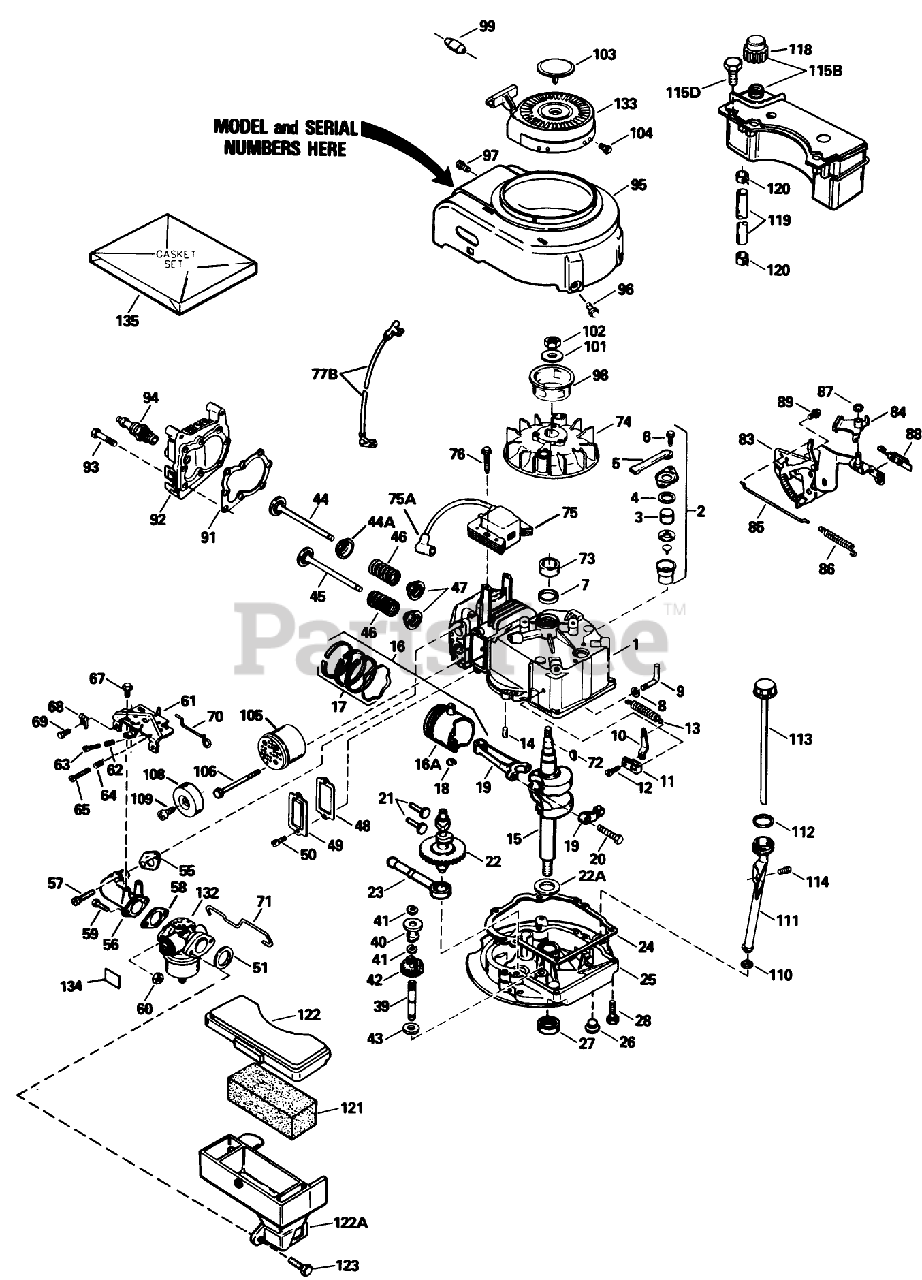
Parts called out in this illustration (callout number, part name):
1	Cylinder Assy. (Incl. #24)
2	Breather Assy. (Incl. Ref. #46 thru 51)
3	Element-Breather
4	Gasket-Breather
5	Tube, Breaker
6	Screw (10-24 x 9/16)
7	Seal-Oil
8	Washer-Flat
9	Rod, Governor (Incl. No. 36)
10	Governor Lever
11	Clamp-Lever, Governor
12	Screw
13	Spring Governor
14	Pin-Dowel
15	Crankshaft
16	Piston-Pin Ring Assy. (Std.)(Incl. Ref. #16A, 17 18)
16	Piston-Pin Ring Assembly (.010 oversize)(Incl. Ref. #16A, 17 18)
16	Piston, Pin Ring Assy. (.020 Oversize)(Incl. Ref. #13A, 14, 15)
16A	Piston Pin Assy. (Std.)(Incl. Ref. #14)
16A	Piston Pin Assembly (.010 oversize)(Incl. Ref. #18)
16A	Piston Pin Assy. (.020 Oversize) (Incl. Ref. #14)
17	Ring Set-Piston (Std.)
17	Ring Set, Piston(.0100versize)
17	Ring Set (.020" OS)
18	Ring-Retaining, Piston Pin
19	Rod Assy., Connecting (Incl. Ref. #17)
20	Bolt-Rod, Connecting
21	Lifter-Valve
22	Camshaft(Mech.Comp. Release)
22A	Washer-Thrust
23	Oil Pump ASM
24	Gasket
25	Flange-Mounting (Incl. Ref. #26, 27 39)
26	Plug Oil Drain
27	Seal-Oil
28	Screw (1/4-20 x 1-1/4)
39	Shaft-Governor
40	Spool-Governor
41	Ring-Retaining
42	Governor Gear ASM
43	Washer
44	Valve, Intake (Std.) (Incl. Ref. #40)
44	Valve, Intake (1/32" oversize)(Incl. No. 40)
44A	Seal Assy., Intake
45	Valve, Exhaust (Std.)(Incl. No. 40)
45	Valve, Intake (1/32" oversize)(Incl. No. 40)
46	Spring-Valve
47	Cap-Valve, Spring
48	Gasket-Cover, Valve
49	Cover-Valve
50	Screw
51	Gasket-Cleaner, Air
55	Gasket-Intake Pipe
56	Pipe-Intake (Incl. Ref. #59)
57	Screw (1/4-20 x 1)
58	Gasket
60	Nut and Lock Washer (1/4-28)
61	Control Assy.-Remote Speed (Incl. Ref. #69 thru 72 76)
62	61709/GIL1515A/95-5
63	Screw
64	Spring-Compression
65	Screw
67	Screw (10-24 x 9/16)
68	Conduit
69	Screw (10-32 x 3/8)
70	2035A67 ADD.ASSEMBL
71	Link-Throttle
72	Key-Flywheel
73	Spacer
74	Flywheel
75	Solid State
75A	Cover-Spark Plug
76	Screw
77B	Ground Wire
83	Bracket-S.E. Brake
84	Lever-Brake
85	Link-Control
86	Spring-Extension
87	Ring-Retaining
88	Terminal
89	Screw (1/4-20 x 3/8)
91	Gasket-Cylinder Head
92	Head-Cylinder
93	Screw (5/16-18x1-1/2)
94	Spark Plug-Resistor (R J19 L M)
95	Housing-Blower
96	Screw (1/4-20 x 1/2)
97	Screw (10-24 x 9/16)
98	Hub-Starter
99	Retainer-Starter Rope
101	Washer-Belleville
102	Nut-Flywheel
103	Plug Starter
104	Screw, Hex Hd.
105	Muffler (Incl. Ref. #122)
106	Screw
108	Cover-Muffler
109	Screw (8-32 x 3/8)
110	Gasket
111	Oil Fill Tube
112	O-Ring
113	Dipstick
114	Screw (10-32 x 1/2)
115B	Tank Assembly-Fuel (Incl. Ref. #102)
115D	Screw (10-32 x 35/64)
118	Cap-Fuel
119	Line-Fuel
120	Clamp-Line, Fuel
121	Filter-Air Cleaner
122	Cover Air Cleaner
122A	Body Air cleaner
123	Screw
132	Carburetor (Incl. Ref. #83)
133	Starter-Rewind
134	Decal-Primer
135	Gasket Set (Incl. Items Marked *)
